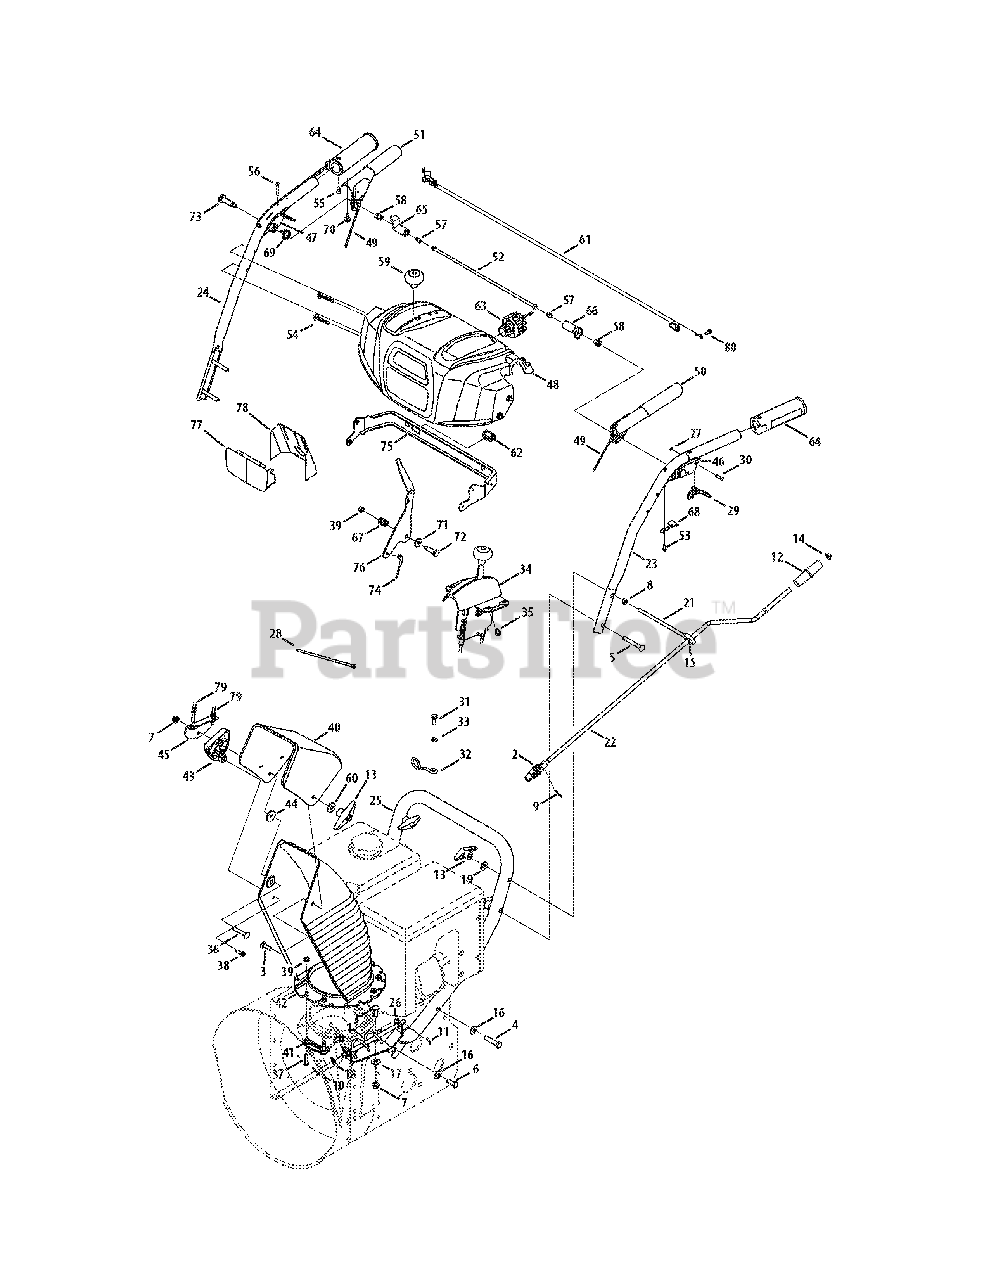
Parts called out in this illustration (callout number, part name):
1	Chute Crank Assembly
2	Joint Block Assembly
3	Screw, Carriage, 5/16-18 x 1.0
4	Screw, Hex, 3/8-16 x 2.00 Lock, Gr5
5	Screw, Carriage, 5/16-18 x 2.5
6	Screw, Hex, 3/8-16 x 1.0 Lock, Gr5
7	Flange Lock Nut, 5/16-18
8	Hex Nut, 5/16-18
9	Internal Cotter Pin
10	Internal Cotter Pin
11	Spring Pin
12	Knob, Crank
13	Knob, Wing Nut, 5/16-18
14	Cap, Push, 3/8
15	Grommet, Rubber
16	Washer, Bel, .375 x .87 x .063
17	Washer, Flat, .349 x .879 .063
18	Washer, .375 x .738 x .063
19	Washer, Belleville, .34 x .872 x .06
20	Plastic Bushing, .380 I.D.
21	Eye Bolt
23	Handle, Upper - LH
24	Handle, Upper - RH
25	Handle, Lower
26	Chute Crank Bracket
27	Ring, Retainer
28	Cable Tie
29	Trigger
30	Pin, 3/16
31	Hex Head Screw, MB 1.25
32	Cable Guide
33	Flat Washer, .330 x .630 x .0635
34	2-Way Chute Control™ Assy
35	Hi-Lo Screw, 1/4-15 x 0.5
36	Bolt, Carriage, 5/16-18 x 1.75
37	Screw, 1/4-20 x 1.00
38	Hi-Lo Screw, 1/4-15 x .75
39	Flange Lock Nut, 1/4-20
40	Upper Chute
41	Chute, Flange Keeper
42	Lower Chute
43	Chute Tilt Cable Guide
44	Flat Washer
45	Cable Bracket
46	Handle Clutch Lock - LH
47	Handle Clutch Lock - RH
48	Handle Panel
49	Cable Assembly, Auger/Drive
49	Cable, Clutch
49	Spring, Extension
50	Handle Engage Assy - LH
51	Handle Engage Assy - RH
52	Rod Ass’y, Clutch Lock Pivot
53	Screw, #8-16 x 0.50
54	Screw, 1/4-20 x 1.625
55	AB Screw, #10-16
56	Screw, #10-24 x 0.375
57	Screw, 1/4-20 x.375
58	Shoulder Nut, 1/4-20
59	Shift Knob
60	Flat Washer, .349 x .879 x .063
61	Wiring Harness
62	Htd. Hand Grip on/off Switch
63	Light Socket
64	Heated Hand Grip
65	Lock Plate
66	Clutch Lock Cam
67	Compression Spring
68	Clutch Lock Spring
69	Torsion Spring
70	Rubber Bumper
71	Flat Washer, .385 x .87 x .06
72	Shoulder Screw
73	Shoulder Screw, 1/4-20 x 1.345
74	Speed Selector Cable
75	Panel Bracket
76	Shift Lever
77	Lens Panel
78	Reflector Label
79	Cable, Chute Tilt
80	Self-Tap Screw
